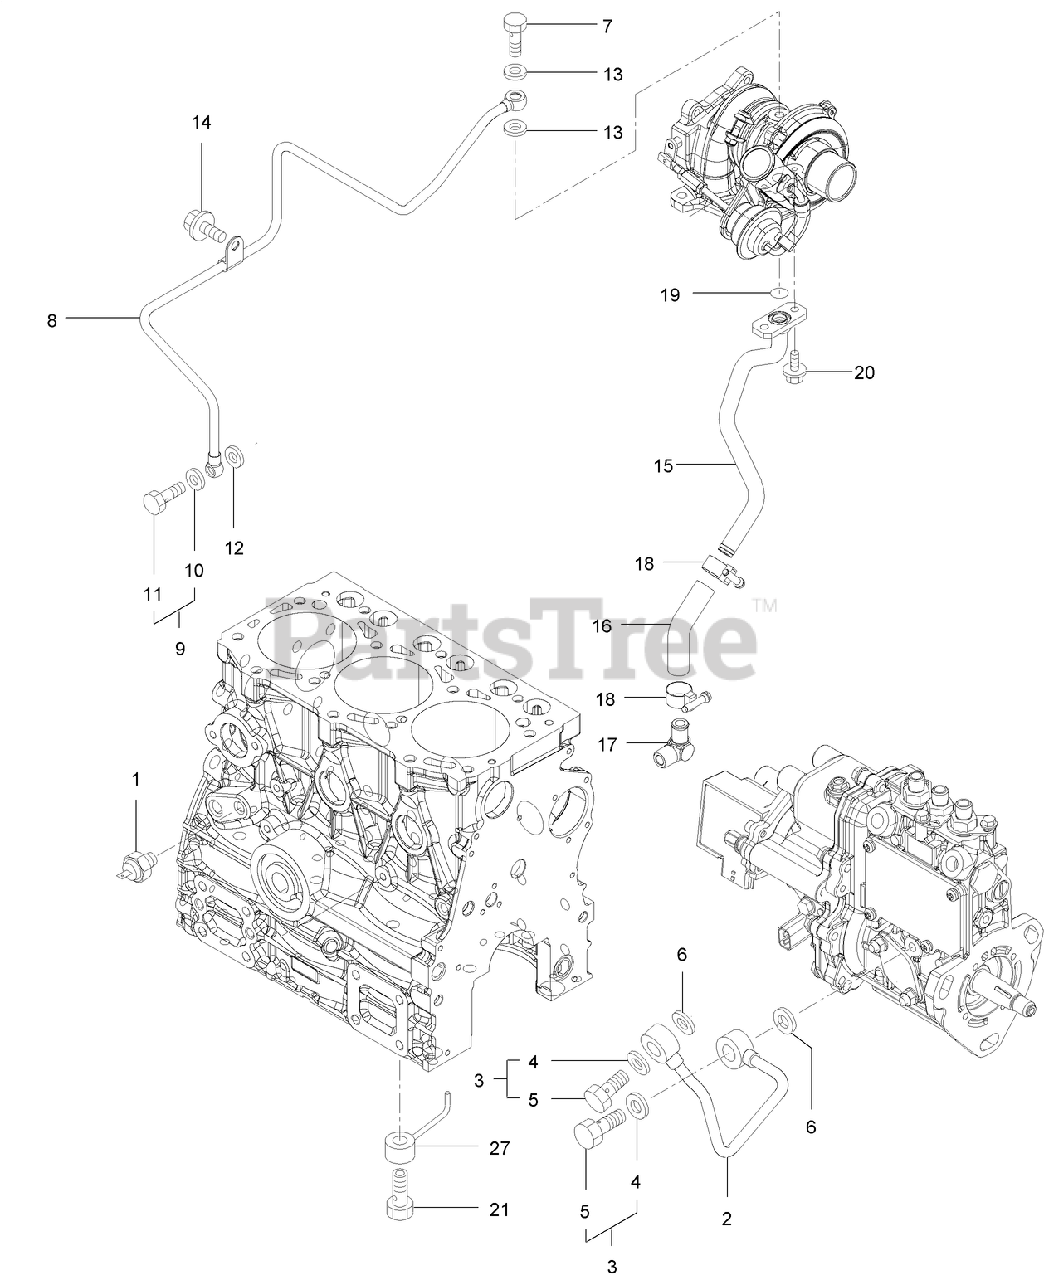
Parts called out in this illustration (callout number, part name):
1	SWITCH-OIL
2	PIPE-OIL
3	JOINT BOLT ASM
4	WASHER-SEAL
5	BOLT-JOINT
6	WASHER-SEAL
7	BOLT-JOINT, PIPE
8	PIPE ASM-LO
9	JOINT BOLT ASM
10	WASHER-SEAL
11	BOLT-JOINT
12	WASHER-SEAL
13	GASKET
15	PIPE-LO RETURN
18	CLAMP-HOSE
19	O-RING
21	VALVE ASM-CHECK
27	NOZZLE ASM-PISTON
